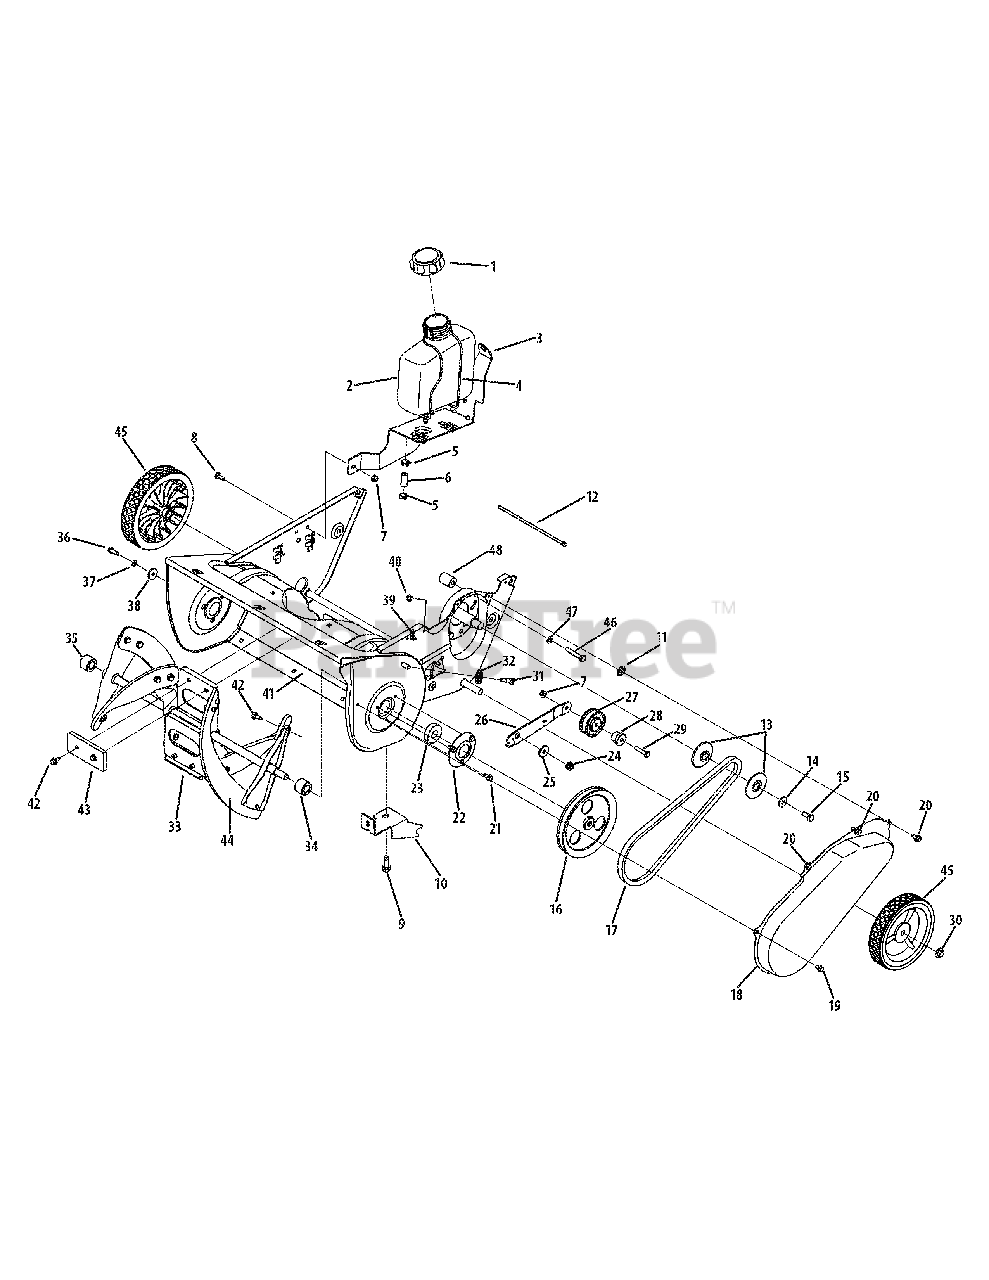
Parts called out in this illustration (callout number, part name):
1	Fuel Cap
2	Fuel Tank, 2 Qt.
3	Fuel Tank Bracket
4	Fuel Tank Support Wire
5	Hose Clamp, .490
6	Fuel Line Hose
7	Flange Lock Nut, 1/4-20
8	Hex Bolt, 1/4-20 x .620
9	Screw, 3/8-16 x 1.000
10	Engine Bracket
11	Push Nut, .25 ID x .50 OD
12	Cable Tie, 7.5"
13	Pulley Half, .625 ID x .225 OD
14	Bell Washer, .340 x .872 x .060
15	Hex Bolt, 5/16-24 x .750
16	Pulley, 1/2 x 6.00
17	V-Belt
19	Hex Screw, 1/4-20 x .375
20	Hex Screw, 1/4-14 x .625
21	Hex Screw, 1/4-14 x .500
22	Bearing Cup
23	Ball Bearing, .625 x 37 x 12
24	Flange Lock Nut, 5/16-18
25	Shoulder Spacer
26	Idler Bracket
27	Idler Pulley Assembly, 1.917
28	Shoulder Spacer, .280 x .785 x .538
29	Hex Screw, 1/4-20 x 1.25
30	Push Cap, 1/2
31	Shoulder Screw,
32	Cable Roller
33	Auger Assembly, 21"
34	LH Spacer
35	RH Spacer
36	Hex Screw, 1/4-20 x .750
37	Lock Washer, 1/4
38	Flat Washer, .265 x .938 x .120
39	Extension Spring, .33 x 1.12
40	Hex Lock Nut, 1/4-28
41	Auger Housing Assembly, 21" Red
41	Auger Housing Assembly, 21" Green
42	Hex Screw, 1/4-14 x .625
43	Rubber Pad
44	Spiral Crescent
45	Wheel, 7 x 1.61
46	Hex Bolt, 5/16-24 x 1.75
47	Lock Washer, 5/16
48	Spacer, .875 x .320 x1.027
